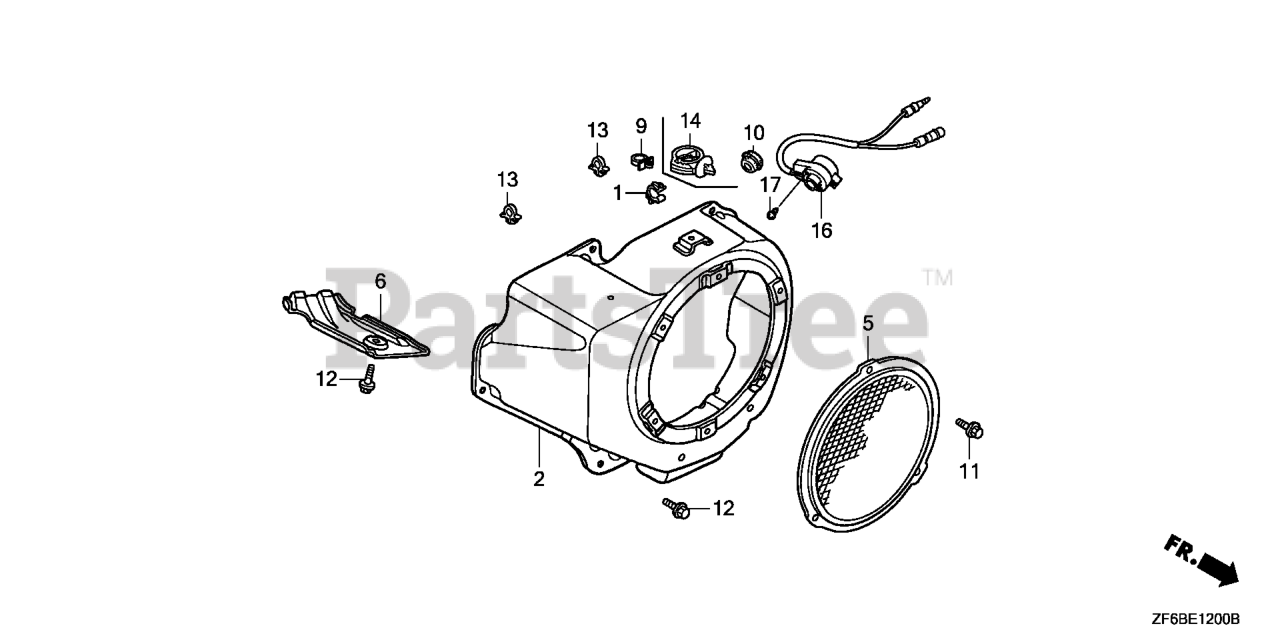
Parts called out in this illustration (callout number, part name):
1	CLIP, TUBE
2	COVER, FAN *R280* (POWER RED)
2	COVER, FAN *NH1* (BLACK)
12	BOLT, FLANGE (6X12) (CT200)
14	CLIP, WIRE HARNESS
16	SWITCH ASSY., ENGINE STOP
17	SCREW, TAPPING (3X6) (PO)
